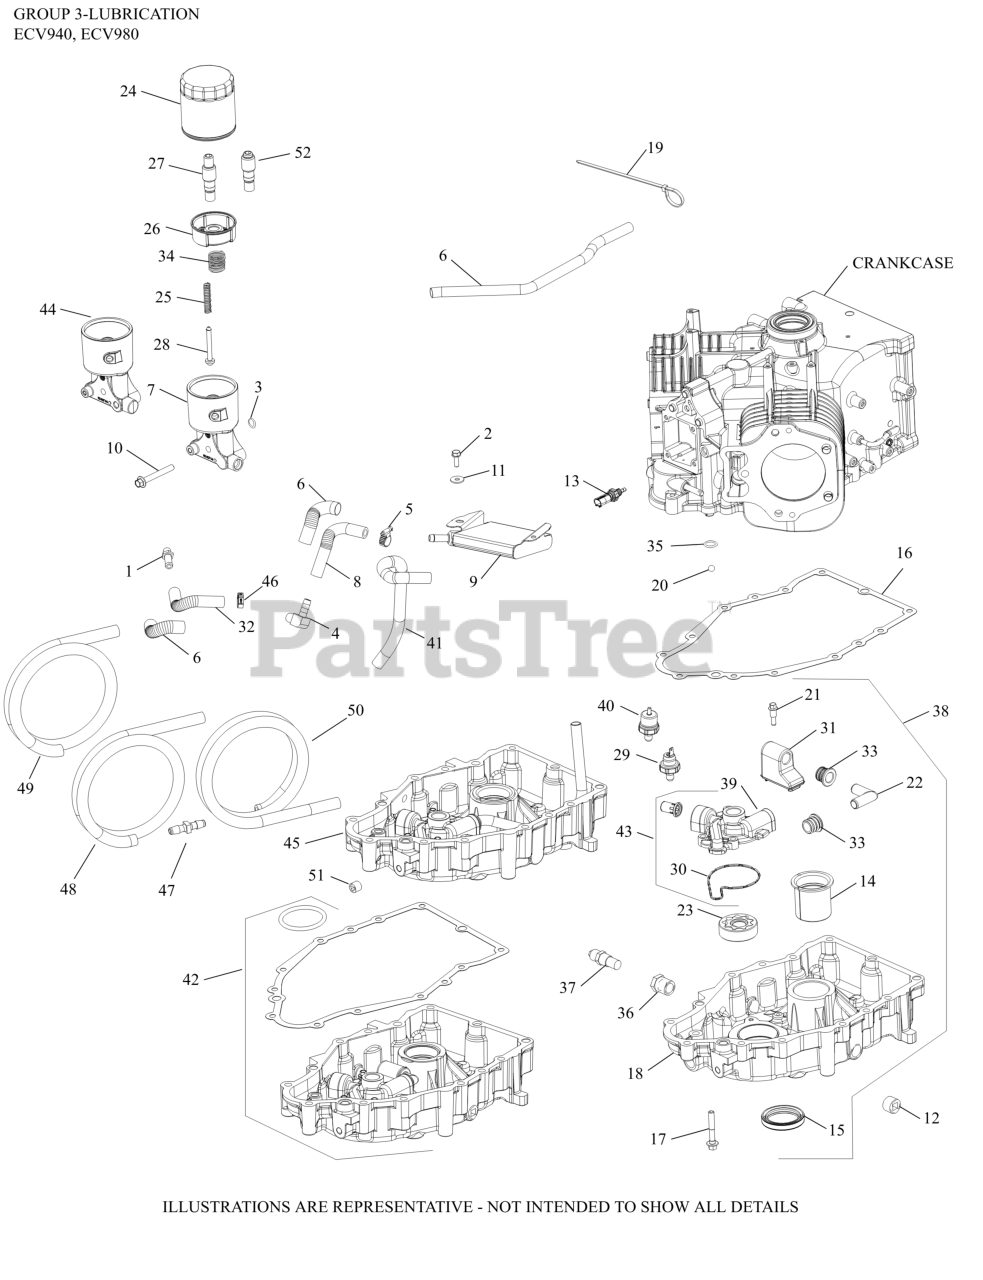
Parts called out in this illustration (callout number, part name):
1	FITTING, HOSE TO PIPE
2	SCREW, TAP M6X1.7X18
3	O-RING, OIL PICK-UP
4	FITTING, 90 DEG. BARBED
6	SLEEVE, ANTI ABRASION-USE 25 431 12-S
7	HOUSING, VERTICAL OIL FILTER - MACHINED
8	HOSE, OIL SUPPLY
9	COOLER, OIL ASSEMBLY
10	SCREW, FLG M8X1.25X60
11	WASHER, FLAT 1/4"
12	PLUG, PIPE 1/2 NPTF SQ CTSK
13	SENSOR, TEMPERATURE
15	SEAL, OIL-(#2503218S)
16	GASKET, OIL PAN
17	SCREW, HEX FLANGE
19	TIE, CABLE
20	KIT, CHECK BALL
21	SCREW, SHD THD FRM M6X.0X6.5
22	TUBE, OIL PICK-UP
23	PUMP ASSEMBLY, OIL/GEROTOR
24	OIL FILTER
25	SPRING, OIL FILTER VALVE
26	CUP, OIL FILTER ASSEMBLY
27	NIPPLE, OIL FILTER ASSEMBLY-(#6213606S)
28	VALVE, OIL FILTER
29	SWITCH, OIL PRESSURE
30	O-RING, OIL PUMP HOUSING
31	HOUSING, OIL PICK-UP ASSEMBLY
32	HOSE, OIL RETURN
33	SEAL, PICK-UP TUBE
34	SPRING, OIL FILTER CUP
38	KIT, OIL PAN
39	HOUSING,OIL PUMP MACH-USE 62 081 38-S
